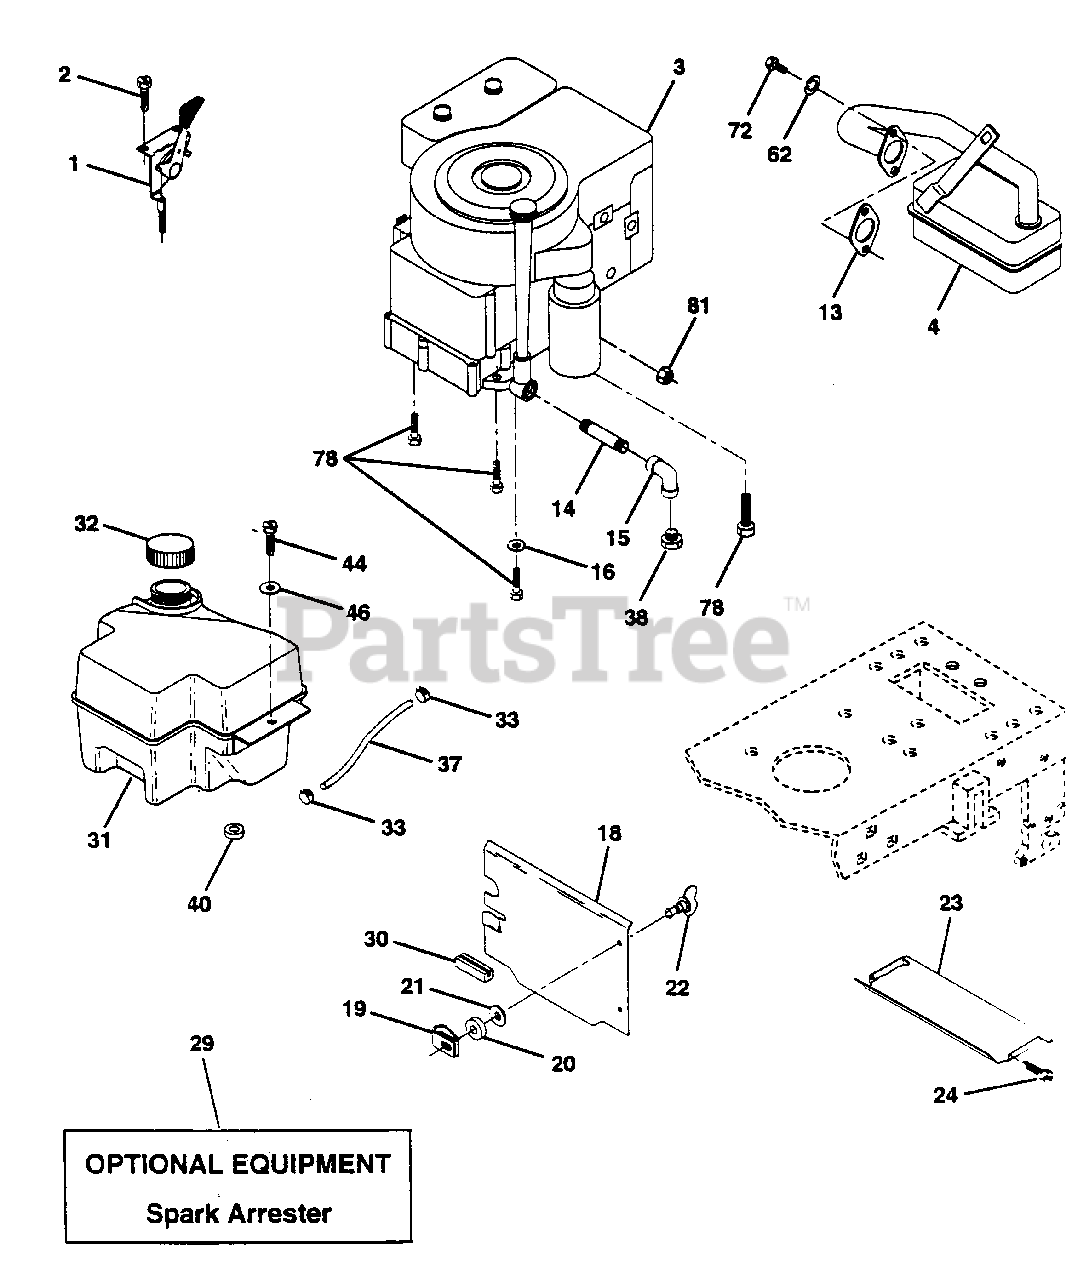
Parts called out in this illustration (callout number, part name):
1	Control Th/ch RH Blk Tee Eec
2	Screw Hex Thd Cut 1/4-20x5/8 T
4	Muffler LT B&s 14 HP IC OHV
13	Gasket Eng 1 313 Id Tin Plated
14	Nipple Pipe 3/8 Npt X 3"
15	Elbow Std 90 Degree 3/8-18 Npt
16	Washer Lock Ext Tooth 3/8
18	Shield Heat LT
19	Receptacle 1/4 Tum dacrotized
20	Retainer 1/4 Tum 365 OD x .222 ID
21	Washer 9/32 x 5/8 x 16 Ga
22	Stud 1/4 Tum (replaces 105751)
23	Shield Heat Browning LT/YT
24	Screw Tap Hex #10-24unc X 1/2
29	Kit Spark Arrestor 1 25
30	Pinch Weld Hood Black 2.00
31	Tank Fuel Front 2.00
32	Cap Asm Fuel W/sym Vented
33	Clamp Hose Blk
37	Line Fuel 9 20"
40	Bushing Snap Nyl Blk Fuel
44	Screw Hexwsh Thdrol 1/4-20x3/4
46	Washer 9/32 X 7/8 X 16ga
62	Washer Lock Hvy Hlcl Spr 5/16
72	Screw Hexhd Cap 5/16-18x3/4
78	Screw Thdrol 3/8-16x1-1/4 TYTT
81	Nut Keps Hex 1/4-20 UNC
